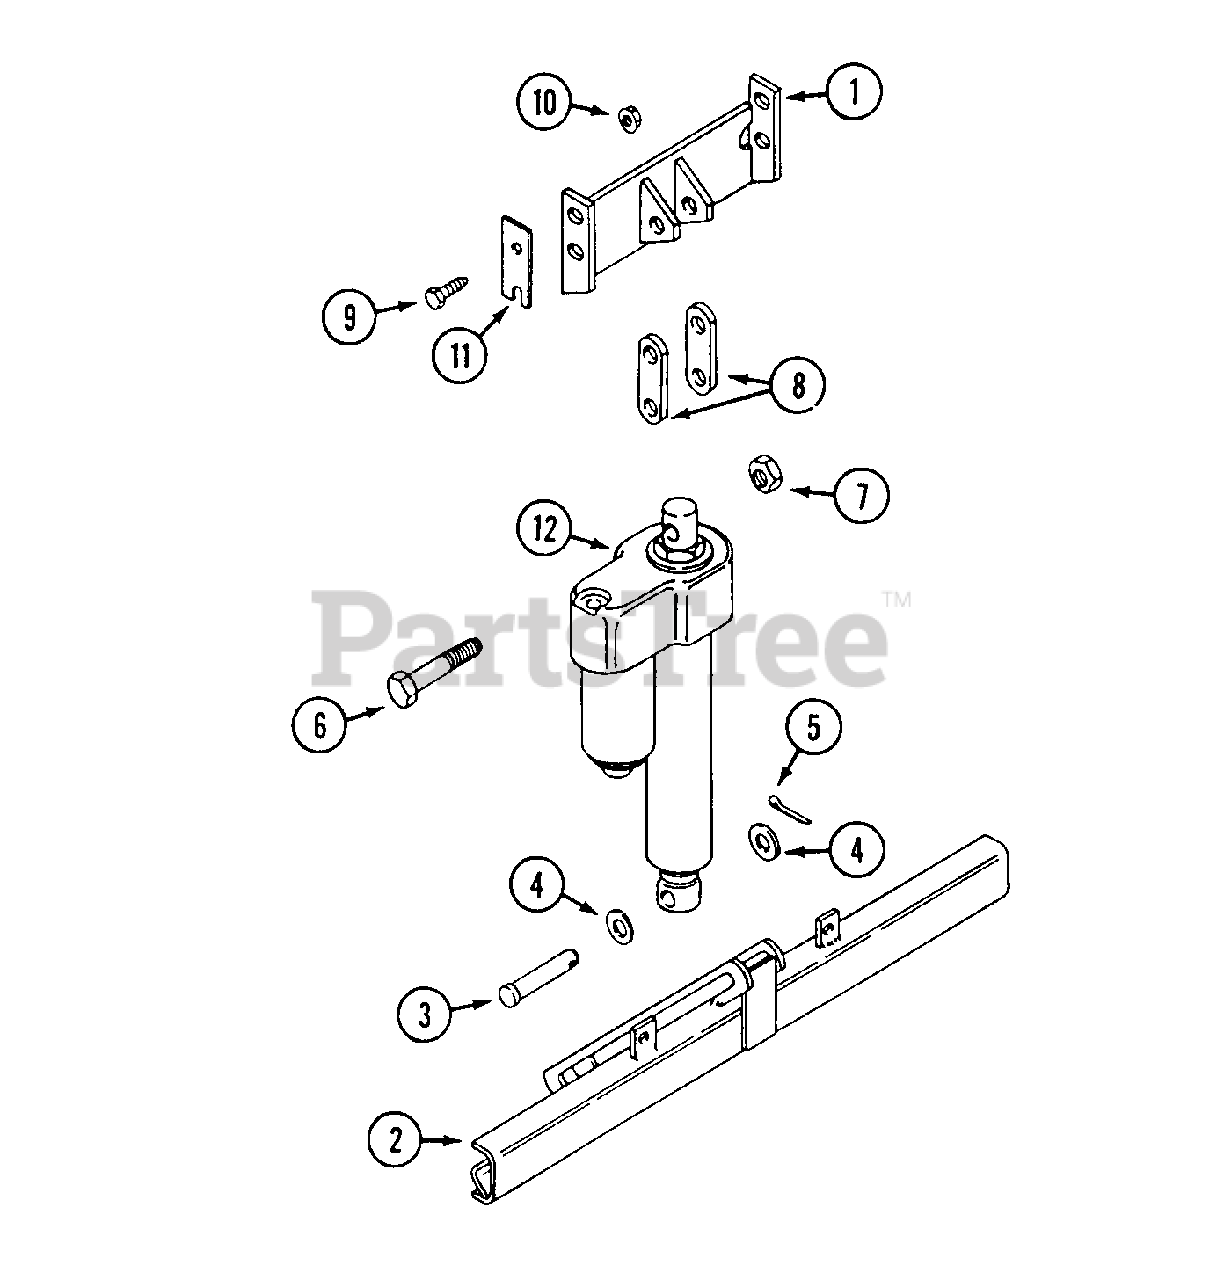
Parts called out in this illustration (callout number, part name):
1	MOUNT - cylinder
3	PIN - clevis 1/2" x 2-1/2"
4	WASHER - 1/2"
5	PIN - cotter 3/32" x 3/4"
6	BOLT - 1/2" - 13 x 2-3/4"
7	NUT - 1/2" - 13 lock
8	LINK - spacer
9	BOLT - 5/16" - 18 x 1"
10	NUT - 5/16" - 18 flange lock
11	SHIM - cylinder mount
12	CYLINDER - lift
